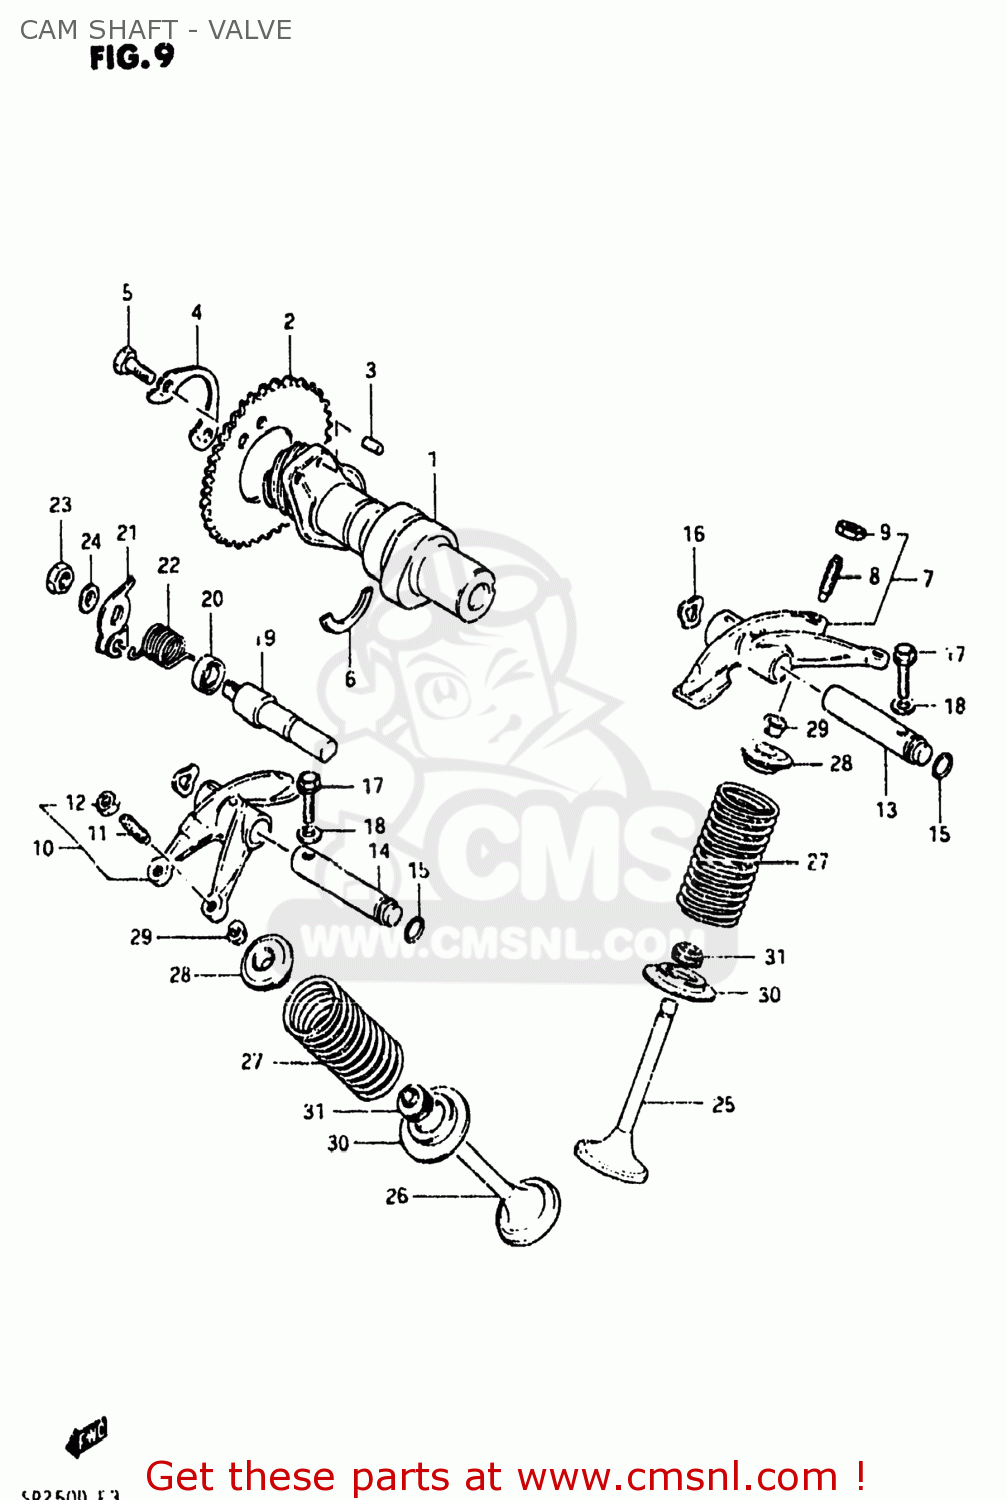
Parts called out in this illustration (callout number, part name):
1	CAMSHAFT
2	SPROCKET,CAMSHAFT(NT:42)
3	PIN
4	WASHER,CAM CHAIN SPROCKET
5	BOLT(6X12.5)
6	C RING
7	ARM,VALVE ROCKER
8	SCREW,TAPPET ADJUSTING
9	NUT,ADJUSTING
10	ARM,VALVE ROCKER,EXHAUST
11	SCREW,TAPPET ADJUSTING
12	NUT,ADJUSTING
13	SHAFT,VLV ROCKER ARM IN(L:91.5
14	SHAFT,VLV ROCKER ARM EXH(L:76)
15	O-RING
16	WASHER
17	BOLT
18	GASKET (NAS)
19	SHAFT,DECOMPRESSION
20	OIL SEAL
21	LEVER,DECOMPRESSION SHAFT
22	SPRING
23	NUT 8MM
24	WASHER
25	VALVE,INTAKE
26	VALVE,EXHAUST
27	SPRING,VALVE
28	RETAINER,VALVE SPRING
29	COTTER VALVE
30	SEAT,VALVE SPRING
31	OIL SEAL
